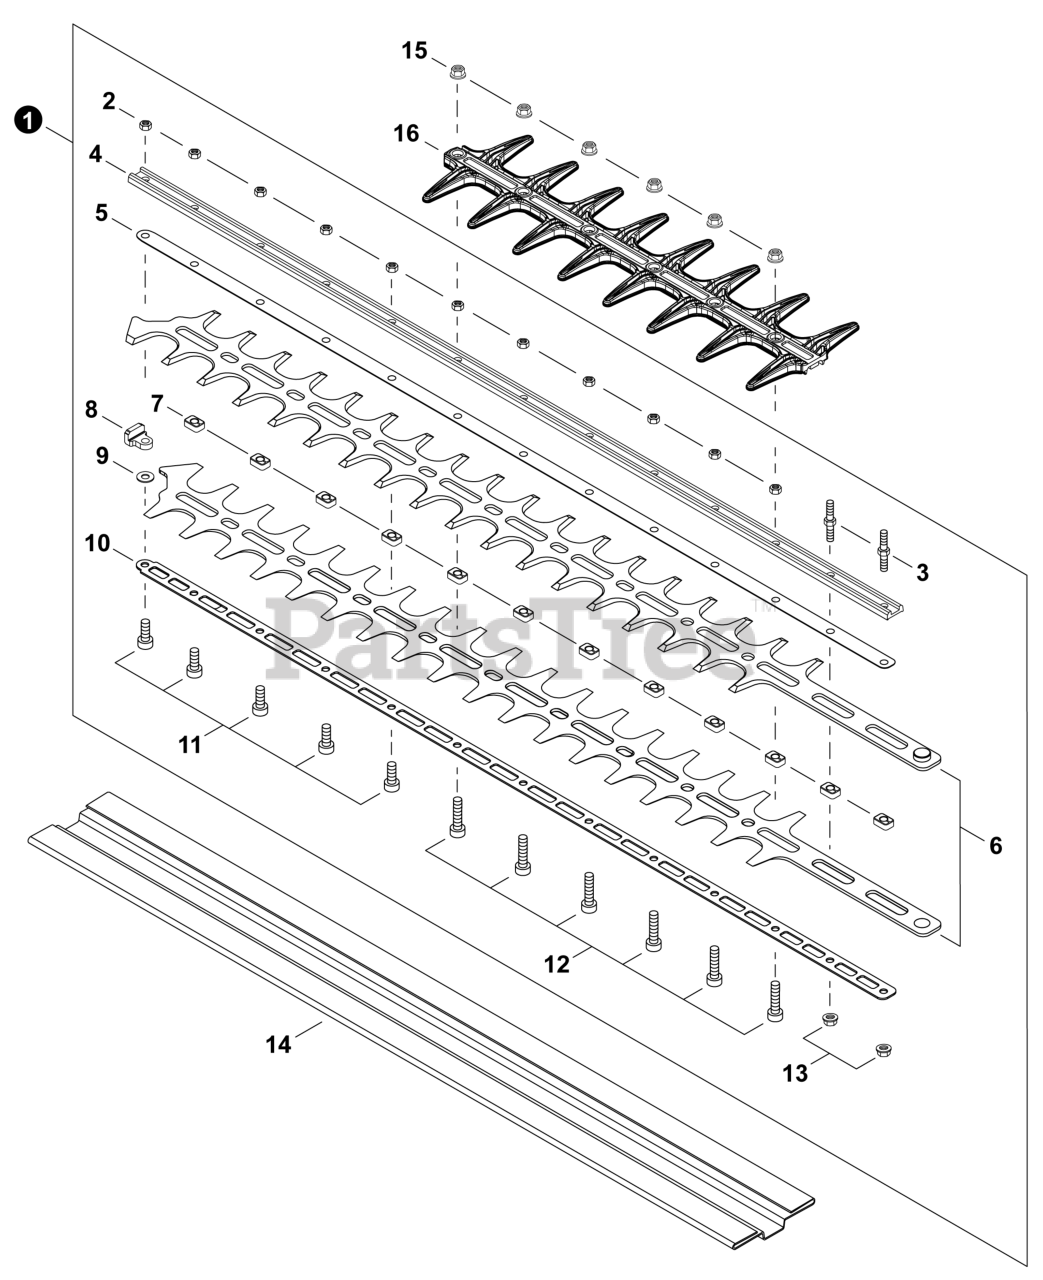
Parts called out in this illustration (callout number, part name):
1	CUTTER ASSY, 30"
3	STUD, MOUNTING M5×36
4	SUPPORT, BLADE 28"
5	SUPPORT, BLADE 28"
6	CUTTER 30"
10	SUPPORT, BLADE 30"
11	BOLT, TORX 5×16
12	BOLT, TORX 5×25
13	NUT, FLANGE M5
14	SCABBARD
15	NUT, FLANGE M5
16	GUARD, CUTTER BLADE
